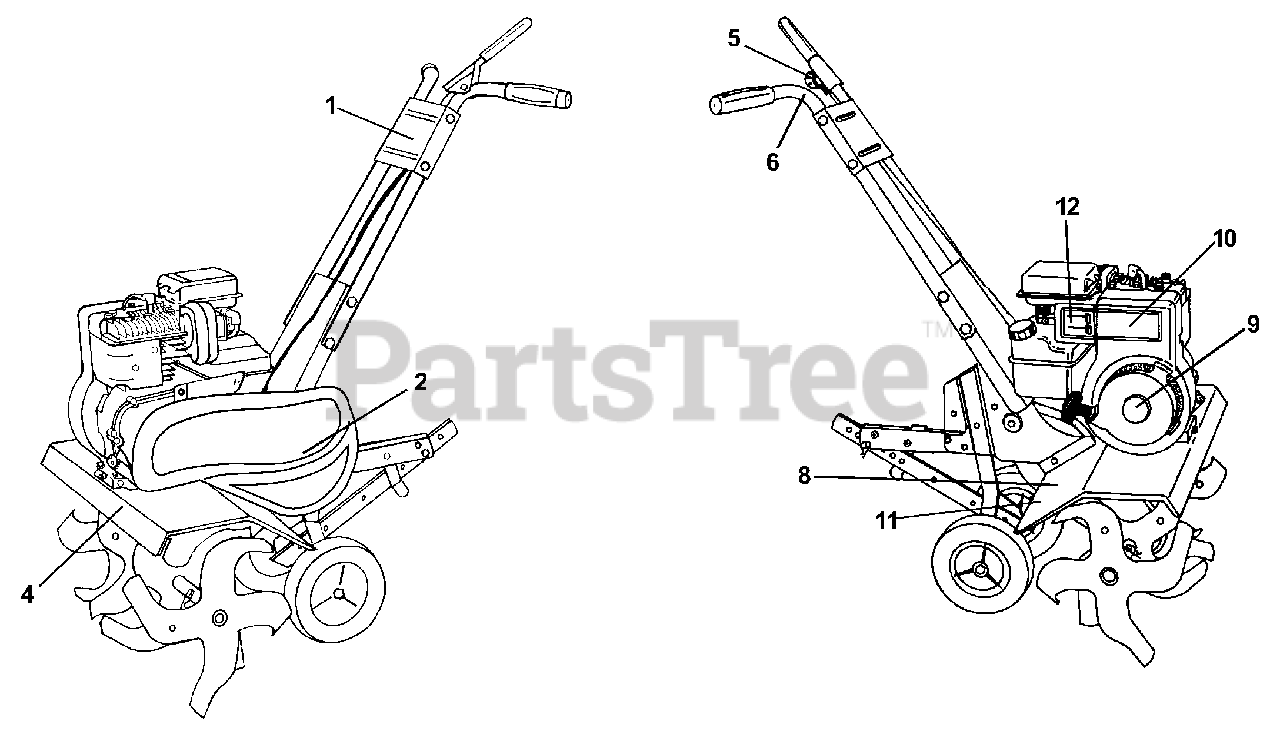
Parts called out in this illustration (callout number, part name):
1	Decal, Logo
2	Decal, Logo
4	Decal, Description
5	Decal, Tine Control
6	Decal, Hand Placement
8	Decal, Warning, Rotating Tines
9	Decal, Briggs & Stratton
10	Decal, 3.5 HP
11	Decal, Warning
12	Decal, Speed Control
